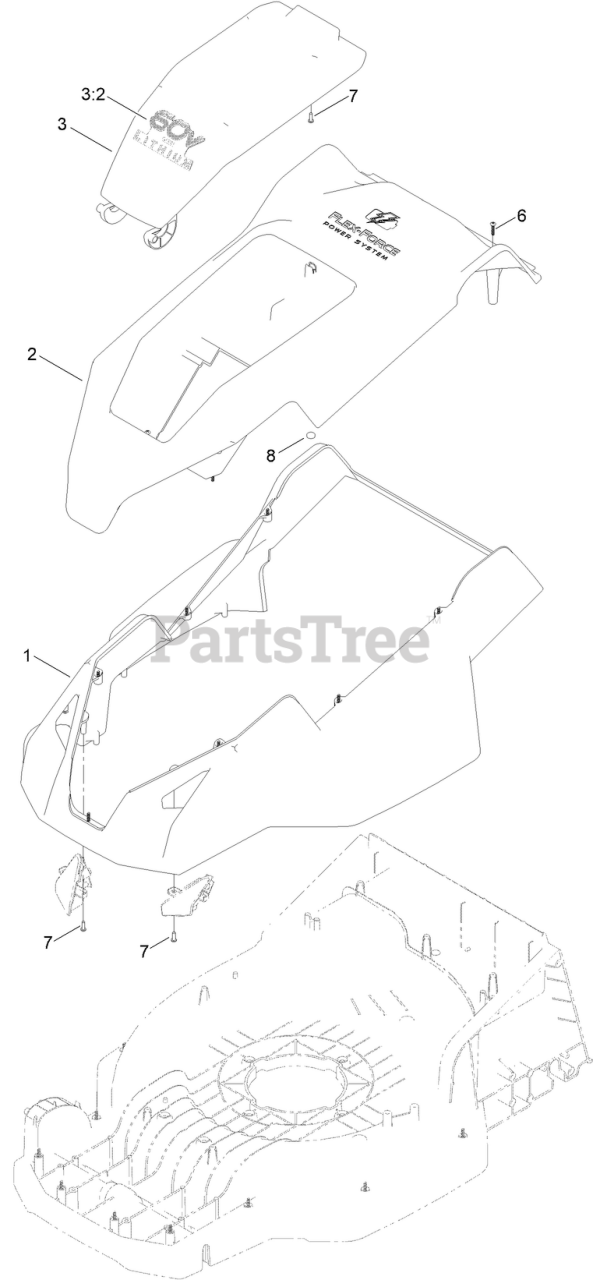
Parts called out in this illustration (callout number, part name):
1	SHROUD-BOTTOM, LED
2	SHROUD-TOP
3	ASM-COVER, BATTERY
3:2	DECAL-60V, LITHIUM
6	SCREW-PPH
7	SCREW
8	MAGNET-COVER
